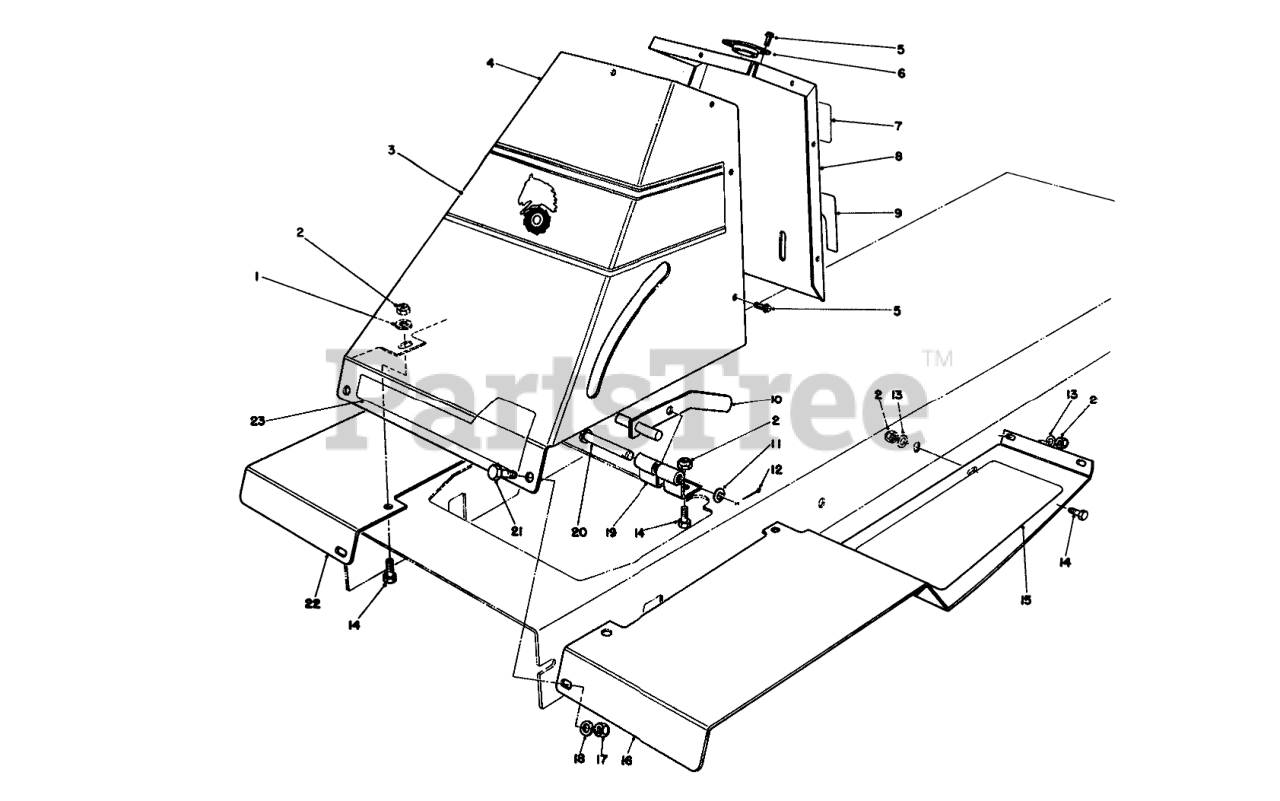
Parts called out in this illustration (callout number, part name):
1	WASHER-FLAT
2	NUT-LOCK, NI
3	DECAL - STEERING SUPT
4	Tower-Front
5	SCREW-HWHTF
6	GUIDE-STRG SHAFT
7	DECAL-DANGER
8	Tower-Rear
9	PARK BRAKE DECAL
10	PARKING BRAKE WA B
11	WASHER-FLAT
12	PIN-COTTER
13	WASHER-PLAIN
14	SCREW-HH
15	FOOT TREAD L.H.
16	Footrest-LH
17	NUT-LOCK, NI
18	WASHER-FLAT
19	Bracket-Parking Brake
20	PIN-CLEVIS
21	SCREW-HH
22	Footrest-RH.
23	DECAL/RECYCLER 32" FRT
